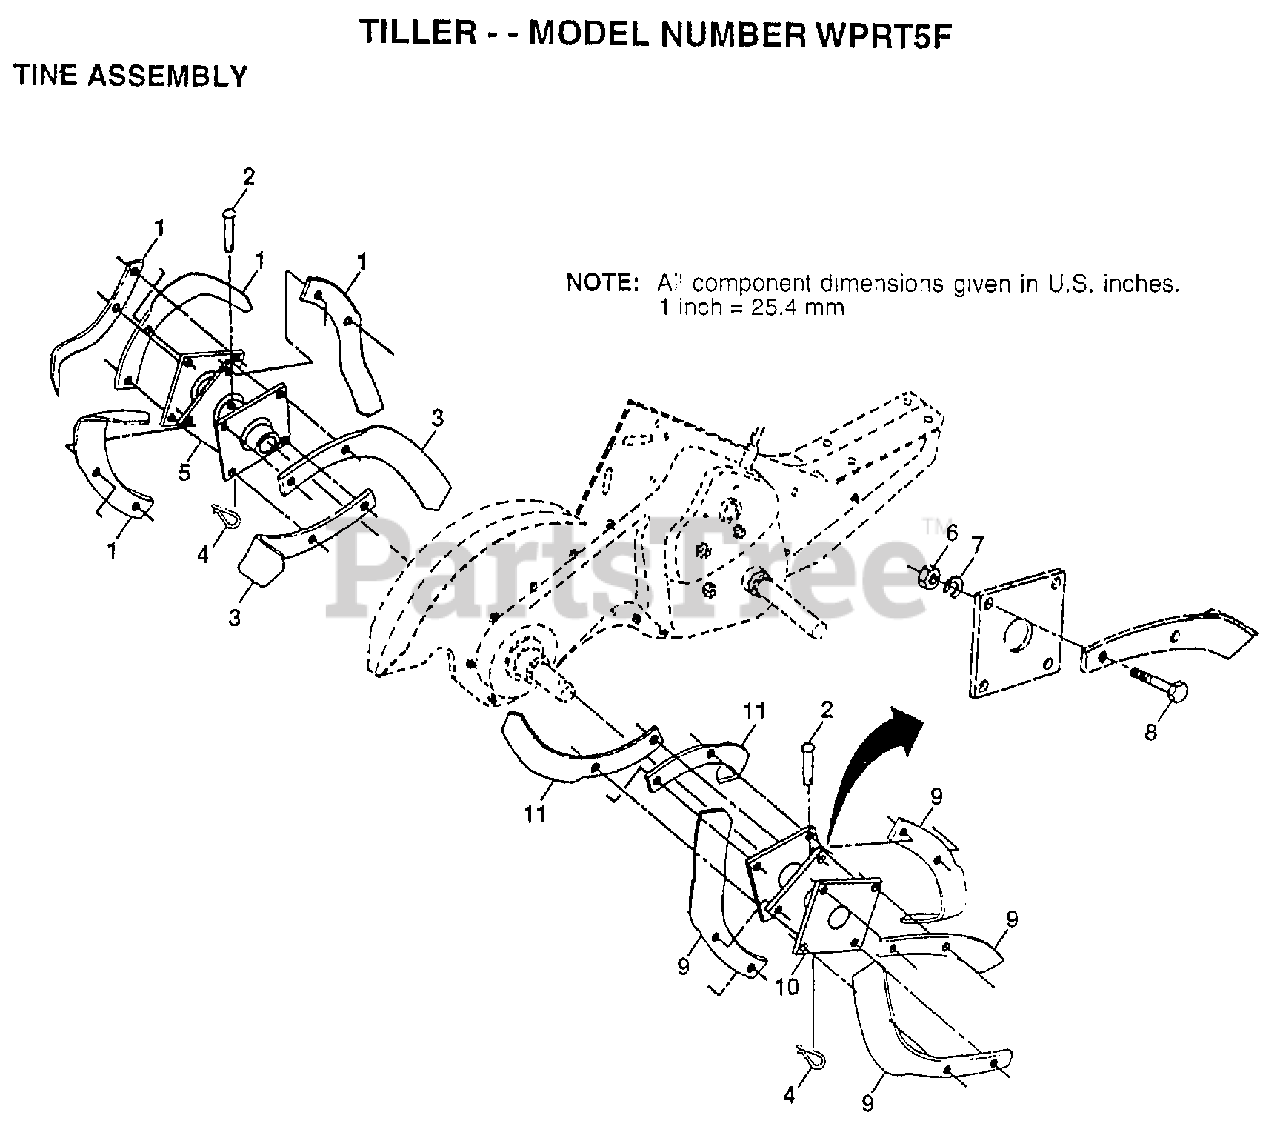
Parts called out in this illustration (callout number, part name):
2	PIN.CLEVIS.SHEAR
3	"TINE.LH.12"""
4	RETAINER.SPRING
5	HUB&PLATE ASM LH
7	LOCKWASHER
8	BOLT
10	HUB&PLATE ASM RH
11	"TINE.RH.12"""
